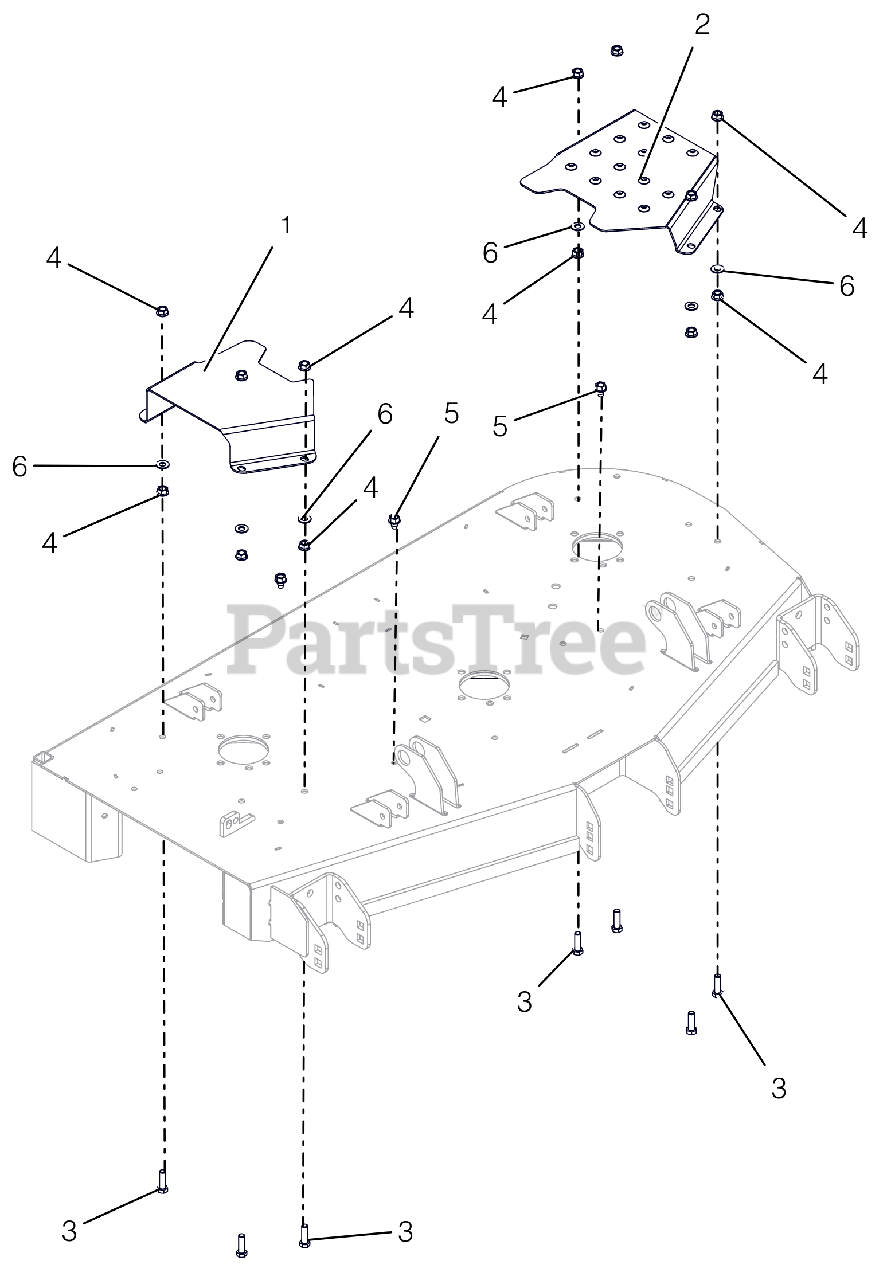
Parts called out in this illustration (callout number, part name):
1	COVER, BELT 48" RIGHT
2	COVER, BELT 48" LEFT
3	@BLT-HEX .38-16X1.25 GR5 YWZC
4	@NUT-SPNLK-FLG .375-16 YWZC
5	@SCR-TAP .38-16X.50 HWH TR YWZ
6	@WSHR-FL-STL.406X.812X.065 YWZ
